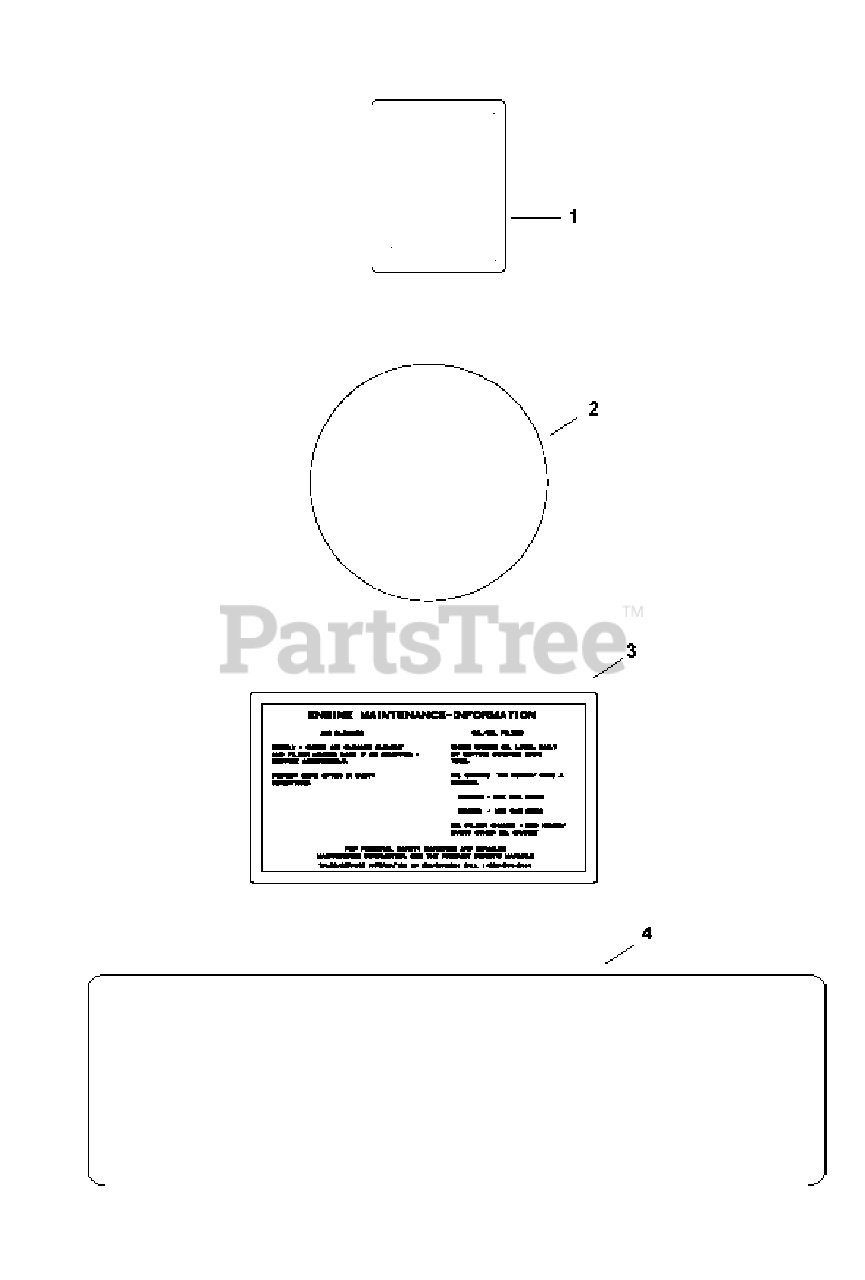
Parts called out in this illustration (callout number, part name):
1	Clear Laminate Decal
2	Command 27 HP Decal
3	Oil Sentry Decal
4	Air Cleaner Decal
